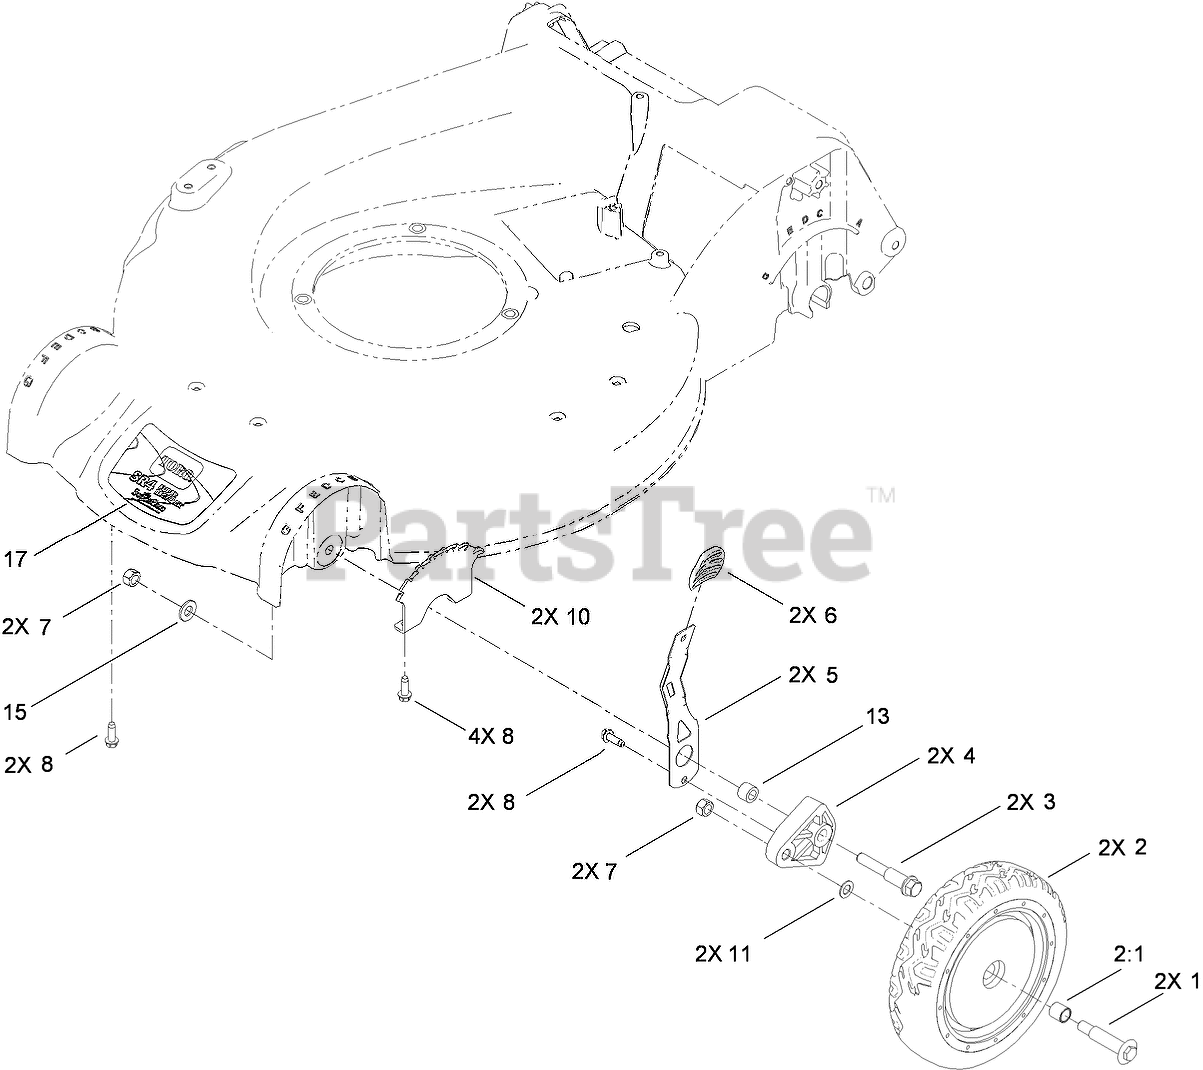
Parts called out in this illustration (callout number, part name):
1	BOLT-SHOULDER
2	WHEEL ASM
2:1	BUSHING
3	SCREW-SHOULDER
4	ARM-PIVOT
5	ARM-SPRING
6	Knob-Lever, HOC
8	SCREW-HWHTF
10	PLATE-HOC
11	WASHER
13	SPACER-WHEEL
15	WASHER-FLAT
17	DECAL-SUPERCARE
